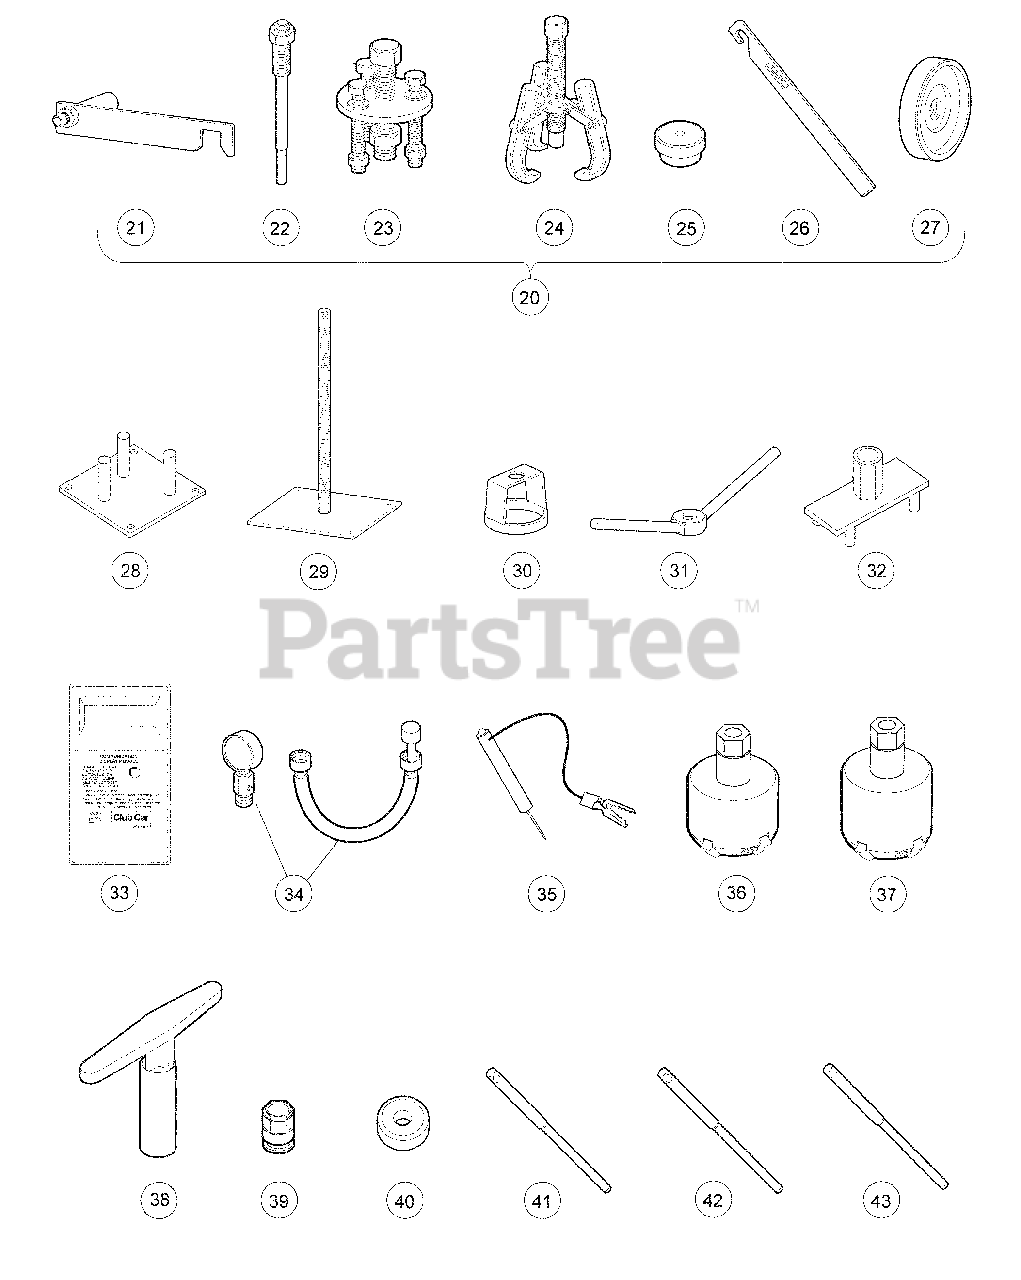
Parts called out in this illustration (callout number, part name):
1	Accelerator Pedal Adjustment Tool
2	Adhesive, Guide Ring, 3-Gram Tube
4	Battery Discharge Machine, 36/48 Volt
5	Battery Terminal Protector Spray
6	Battery Thermometer
7	Bearing and Oil Seal Remover Assembly
8	Bearing Driver Set
9	Bearing Puller
10	Bearing Puller Wedge Attachment
11	Brake Adjustment Tool
12	Brake Cable Release Tool
13	Brake Pedal Adjustment Tool Kit
14	Brake Pedal Adjustment Tool
15	Brake Pedal Tension Tool
16	Calibration Test Module
17	Cam Installation Tool
18	Charger Bezel Tool
19	Clutch Removal Tool (for 4x4 vehicles)
20	Clutch Tool Kit
21	Clutch Alignment Tool
22	Drive Clutch Puller
23	Drive Clutch Hub Puller
24	Driven Clutch Cam Puller
25	Driven Clutch Puller Plug
26	Drive Clutch Holder Tool Assembly
27	Press Weldment
28	Drive ClutchFixed Sheave Tool (for 4x4 vehicles)
29	Driven Clutch Spring Compression Base (for 4x4 vehicles)
30	Driven Clutch Spring Compression Collar (for 4x4 vehicles)
31	Driven Clutch Spring Compression Nut (for 4x4 vehicles)
32	Drive Clutch Spider Removal Tool (for 4x4 vehicles)
33	Communication Display Module
34	Compression Gauge and Adapter
35	Continuity Tester
36	Cutter, Valve Seat, #122
37	Cutter, Valve Seat #115
38	Wrench, T, #505
39	Adapter, T-Wrench
40	Cutter, Valve Seat, 60 Degree
41	Pilot, 6.6 MM
42	Pilot, 6.62 MM
43	Pilot, 6.65 MM
44	Dry Moly Lubricant
45	Flywheel Puller Kit
46	Gauge, Carburetor Float Level
48	Governor Shaft Installation Tool
49	Hydraulic Brake Adjuster (for HUV 4213)
50	Hydrometer
51	Internal Retaining Ring Pliers
52	IQ Display Module (IQDM) Kit
53	IQ Display Module (IQDM-P) Kit
54	Adaptor, Cable
55	IQDM Series 2 Cable
56	IQDM Series 1 Cable
57	Liquid Gasket
58	Moly-Teflon Lubricant (4-oz. (113-gram) tube)
59	Paint, Touch-Up – Beige
59	Paint, Touch-Up – Black
59	Paint, Touch-Up – Burgundy
59	Paint, Touch-Up – Classic Blue
59	Paint, Touch-Up – Dark Gray
59	Paint, Touch-Up – Dark Green
59	Paint, Touch-Up – Gray
59	Paint, Touch-Up – Red
59	Paint, Touch-Up – Royal Blue
59	Paint, Touch-Up – White
60	Paint, Precedent Underbody – Gray
61	Paint Pen, Touch-Up, Precedent Underbody – Black
62	Piston Ring Compressor Kit (FE290, FE350 and FE400 engines)
63	Piston Ring Pliers
64	Puller, Special Use
65	Retaining Ring Pliers, 45° External
66	Retaining Ring Pliers, 90° Internal
67	Safety First Card (50 per pack)
68	Seal Puller
69	Spanner Wrench
70	Steering Column Bearing Press Tool
71	Steering Column Retaining Ring Tool
72	Steering Wheel Puller Tool
73	Tachometer
74	Tachometer Diesel Probe
75	Transaxle Axle Seal Tool
76	Transaxle Pinion Seal Tool
77	Transmission Tool Kit
82	Valve Clearance Adjuster Screw Holder (for FE290 engines only)
83	Valve Guide Driver
84	Valve Guide Reamer (FE290, FE350, and FE400 only)
85	Valve Guide Reamer, 6.6 mm
86	Valve Seat Cutter Guide
87	Valve Seat Cutter T-Wrench
88	Valve Seat Cutter, 45° (32 mm diameter) (for FE290 engines only)
89	Valve Seat Cutter, 45°/30° (35 mm diameter)
90	Valve Spring Compressor
91	Volt Ohm Meter
92	Tool, Tensioning, Starter Generator
